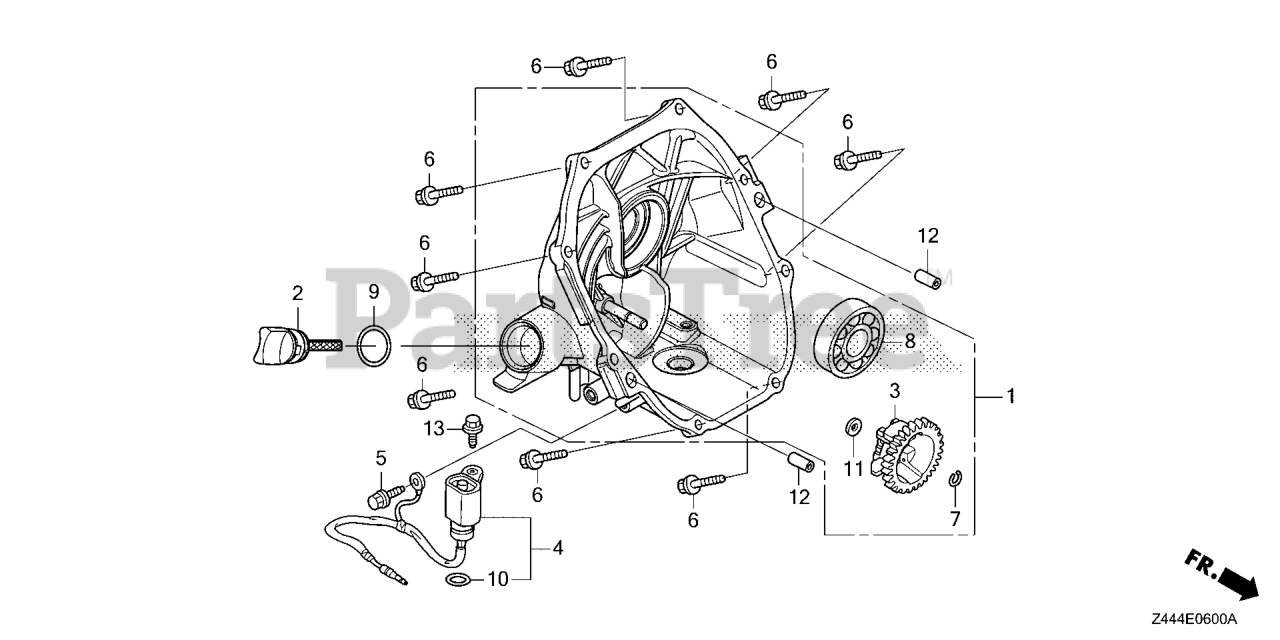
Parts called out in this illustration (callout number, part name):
1	COVER ASSY., CRANKCASE
2	CAP, OIL FILLER
3	HOLDER, GOVERNOR WEIGHT
4	SWITCH ASSY., OIL LEVEL
5	BOLT, FLANGE (6X12) (CT200)
5	BOLT, FLANGE (6X14)
6	BOLT, FLANGE (6X25) Use up to Engine SN 2056819.
7	CLIP, GOVERNOR HOLDER
8	BEARING, RADIAL BALL (62/22)
9	O-RING (25.5X3)
10	O-RING (11.8X2.4)
11	WASHER, PLAIN (6MM)
12	PIN, DOWEL (8X20)
13	BOLT, FLANGE (6X14)
